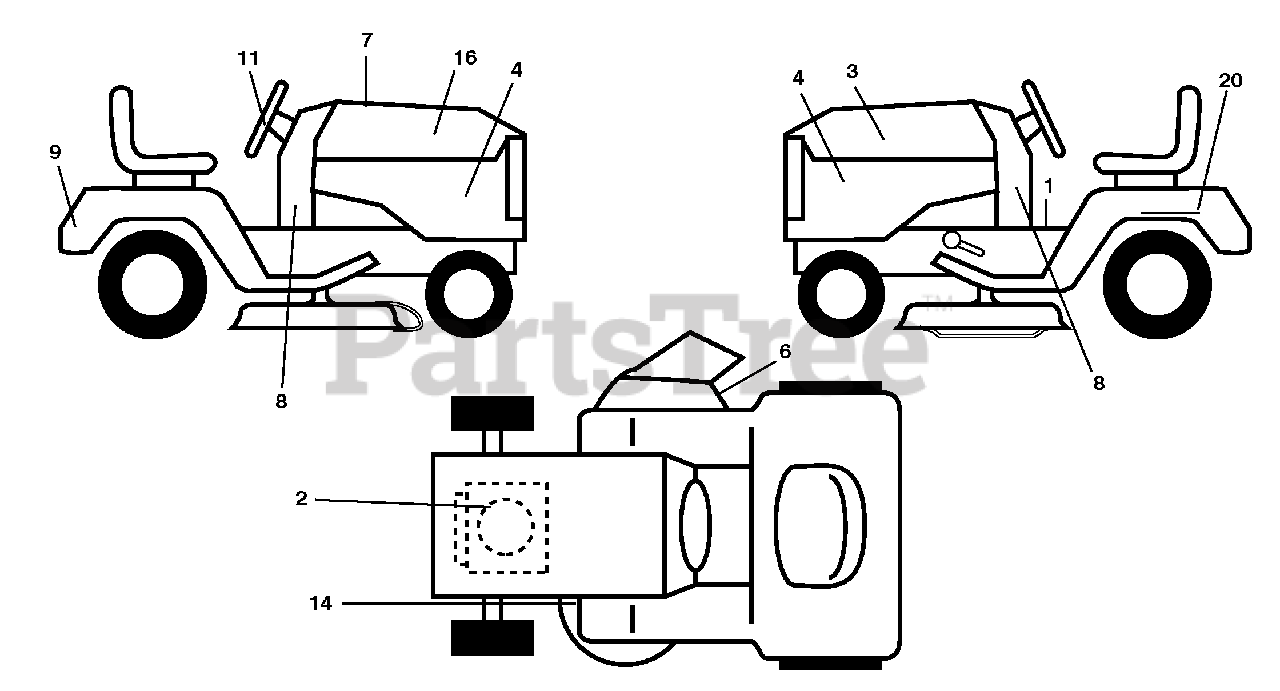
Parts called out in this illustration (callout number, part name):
1	Decal Fender Warning
2	Decal Engine H.P.
3	Decal Hood LH
4	Decal Side Panel
6	Decal Warning, Keep Hand Away
7	Decal Replacement Parts
8	Decal LWRDASH
9	Decal Fender
11	Decal Ins Strg Whl
14	Decal V-Belt Schematic
16	Decal Hood RH
20	Decal Bat Dan/Psn
20	Pad Footrest LH
20	Pad Footrest RH
20	Decal Bypass
20	Manual Operator's E&F
20	Manual Parts
